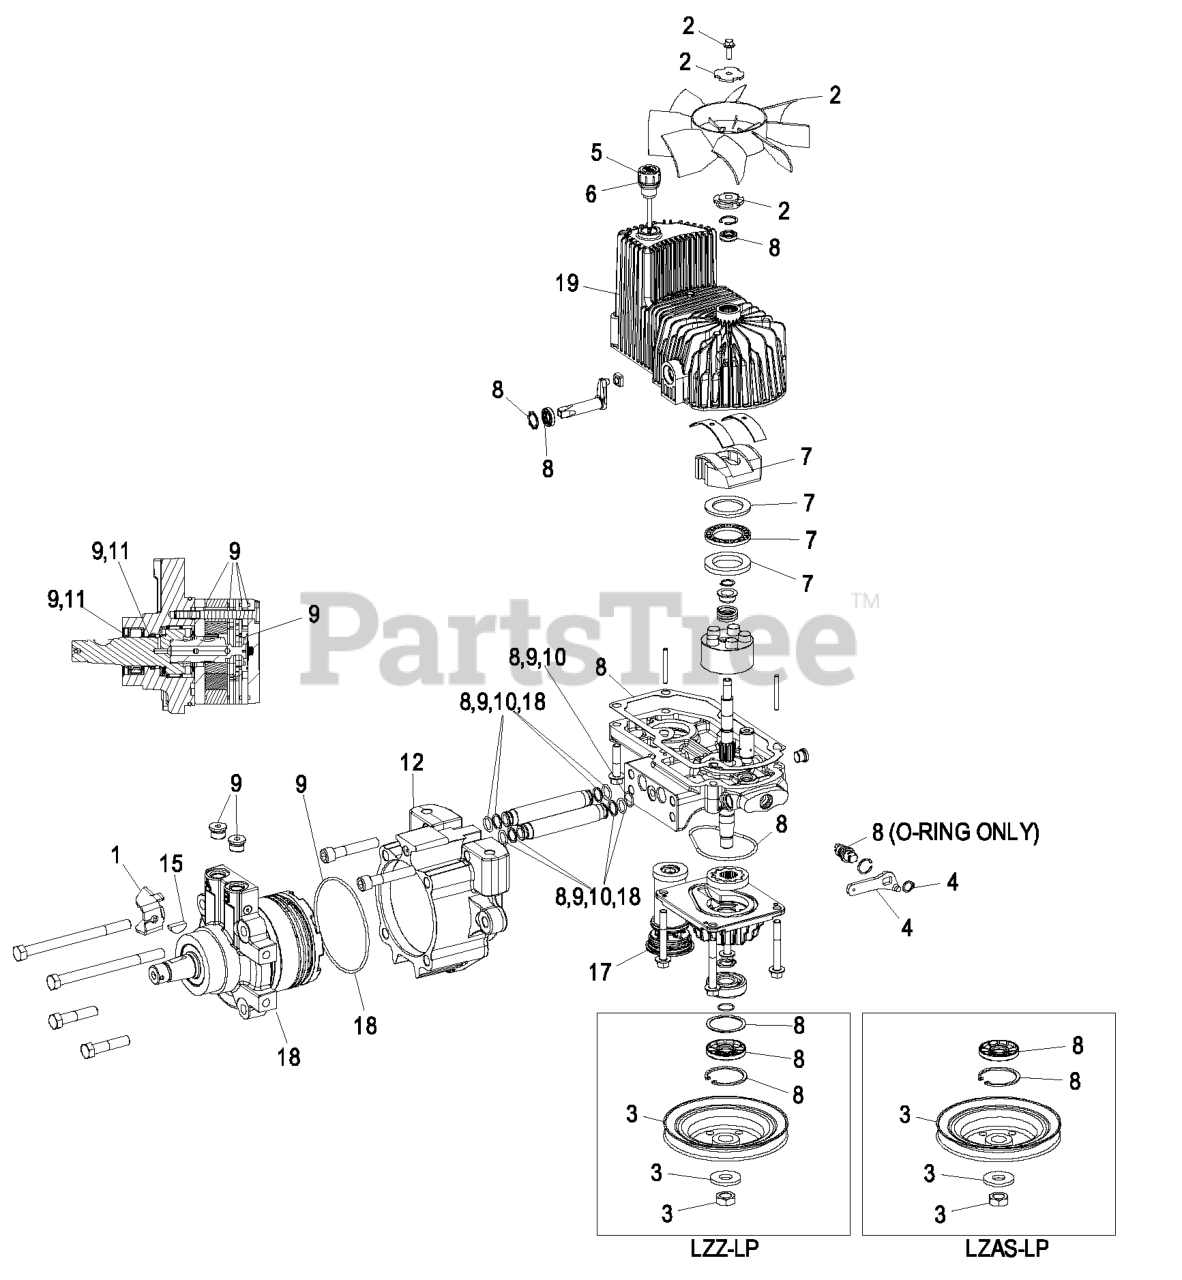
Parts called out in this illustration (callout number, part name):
1	BRACKET-ANCHOR, CABLE
2	FAN KIT
3	PULLEY KIT
4	HANDLE-BYPASS VALVE, HYDRO
5	DIPSTICK-HYDRO W/GASKET
6	GASKET-DIPSTICK, HYDRO
7	SWASH BLOCK KIT
8	PUMP SEAL KIT
9	MOTOR SEAL KIT
10	TUBE SEAL KIT
11	OUTPUT SHAFT SEAL KIT
12	CUP-NOSE
15	KEY-WOODRUFF
17	FILTER-HYDRO
18	MOTOR-HYD, 240CC RH, UNSE
19	HOUSING-HYDRO, LH
